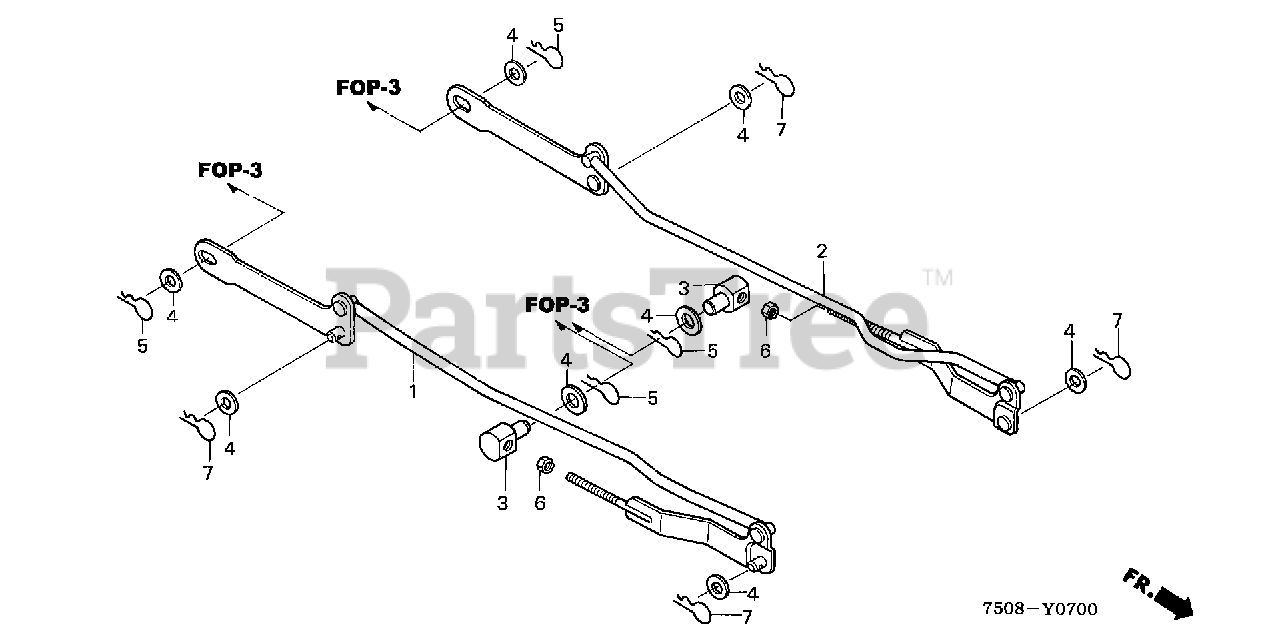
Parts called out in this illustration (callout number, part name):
1	LINK, R. CUTTER DECK
2	LINK, L. CUTTER DECK
3	PIN, FR. LINK ADJUSTING
4	WASHER, SPECIAL (13MM)
5	PIN, LOCK (2.3MM)
6	NUT, HEX. (12MM)
7	PIN, LOCK (12MM)
